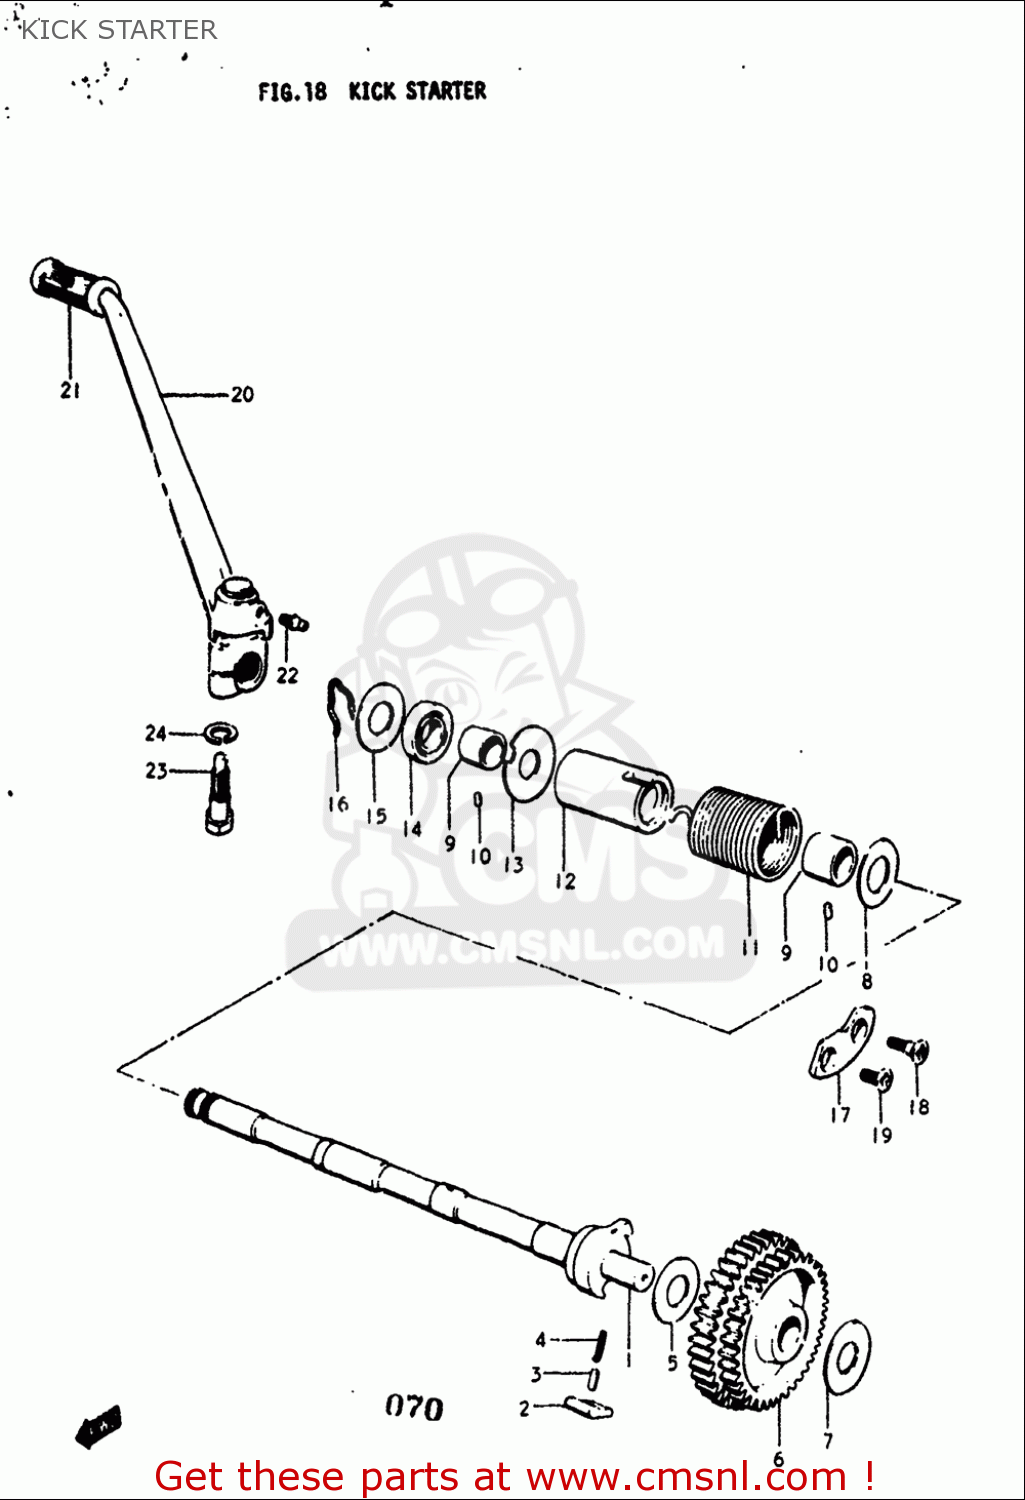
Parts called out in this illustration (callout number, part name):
2	PAWL,KICK STARTER
3	PIN(5X15.5)
4	SPRING
5	WASHER(13X31.5X1.5)
7	WASHER(13X31.5X1.5)
8	WASHER(16X30X1)
10	PIN
11	SPRING
14	SEAL,OIL(16X30X8)
18	SCREW(6X19)
19	SCREW
21	RUBBER,KICK STARTER PEDAL
22	NIPPLE
23	BOLT(10X37.5)
24	WASHER,LOCK
